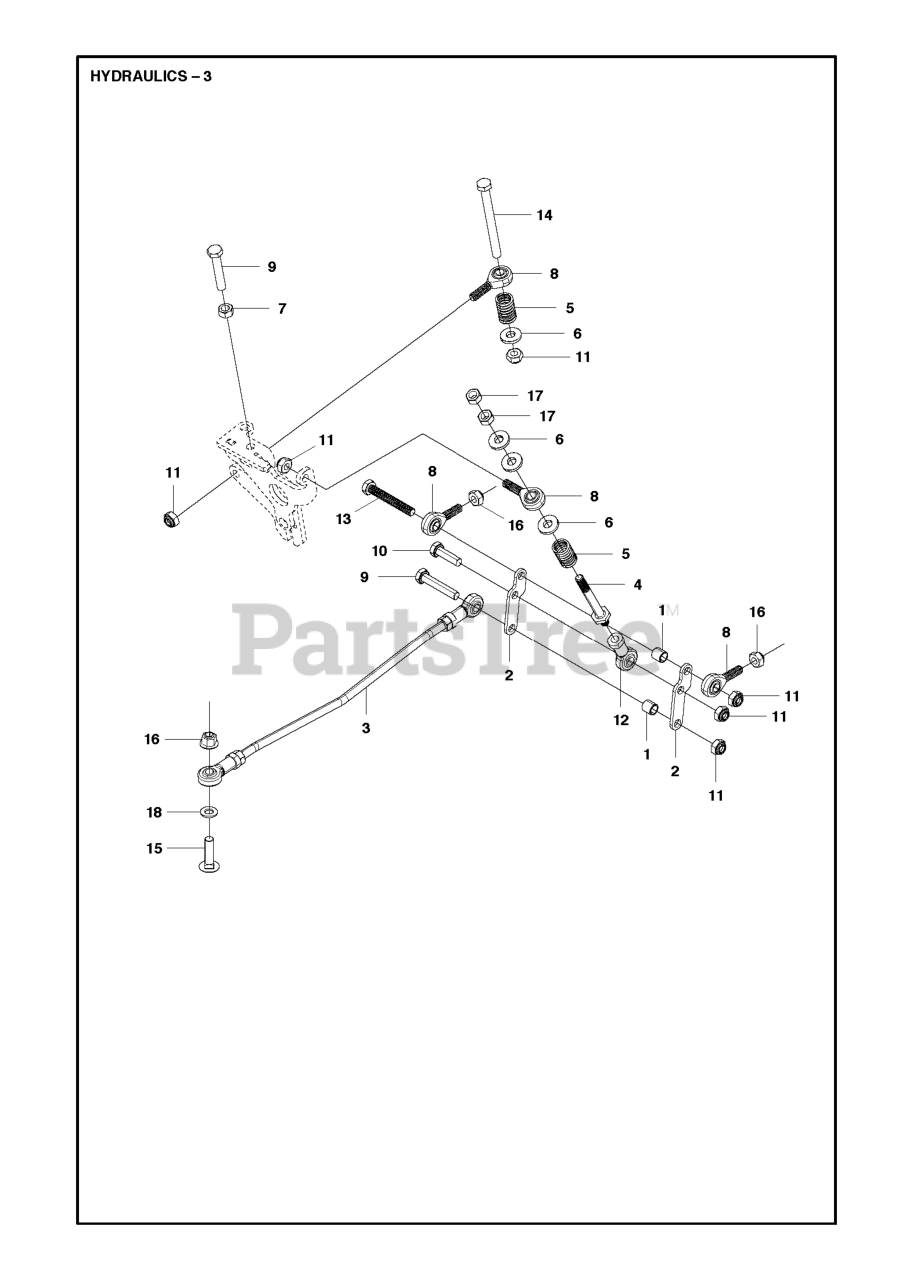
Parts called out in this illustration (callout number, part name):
7	Nut
11	NUT
18	WASHER
